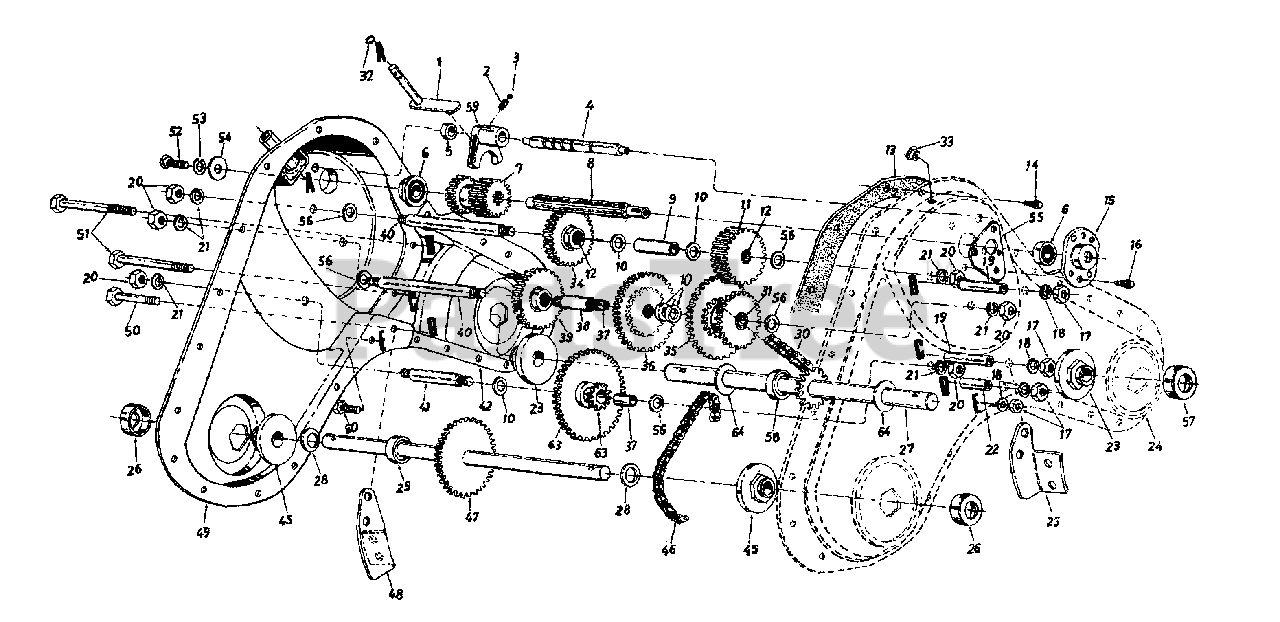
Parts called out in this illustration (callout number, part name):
1	Shifting Bracket Ass'y.
2	Compression Spring .50" Lg.
3	Ball Detent .250" Dia.
4	Detent Shaft 1/2" Dia.
5	Spacer .505" I.D. x .88" O.D.
6	Ball Brg. .62" I.D. x 1.38"
7	Spur Gear 16T (Input)
8	Input Spline Shaft 7/8"
9	Spacer .657" I.D. x 2.85" Lg.
10	Fl-Wash. .640" I.D. x 1.24"
11	Spur Gear 30T 7/8" I.D.
12	Needle Bearing 5/8" I.D.
13	Gasket--Trans. Hsg.
14	Hex S-Tap Scr. 1/4-20 x .5"
15	1-3/8" Dia. Bearing Housing
16	Hex TT-Tap Scr. 1/4-20 x .75"
17	Hex Nut 5/16-18 Thd.
18	L-Wash. 5/16" I.D.
19	Spacer 1.56" Lg.
20	Hex Nut 7/16-20 Thd.
21	Bell-Wash. .45" I.D. x 1.0"
22	Spacer 1.015" Lg.
23	Tine Shaft Brg. 1.002 x 2.50
27	Tine Shaft Ass'y. 1" O.D.
28	Fl-Wash. .76" I.D. x 1.5" O.D.
29	Spacer .75" I.D. x .50" Lg.
30	Chain #50 5/8 Pitch x 52 Links-Endless
31	Needle Bearing 5/8" I.D.
32	Snap Ring
33	Taper Cap Plug
34	Spur Gear 30T 12/16" I.D.
35	30/44T Gear Ass'y. Comp.
36	Spur Gear 44T/11T
37	Sleeve Bearing
38	Gear Hub 3/4" I.D. x 3" Lg.
39	Spur Gear 30T 1.0" I.D. x 1/2" W
40	Jack Shaft 5/8" Dia. x 5"
41	Jack Shaft 5/8" Dia. x 2.38"
45	Wheel Brg..752" x 2.5"
46	#420 Chain 1/2 Pitch x 50 Links-Endless
47	Wheel Shaft Ass'y. 15.6"
51	Hex Bolt 5/16-18 x 2.5"
52	Hex Bolt 1/4-20 x .62" Lg.
53	L-Wash. 3/8" I.D.
54	Fl-Wash. 1/4" I.D. x .93" O.D.
55	Gear Positioner Bracket
56	Fl-Wash. 7/16" I.D. x 1-3/8"
57	Seal 1" Shaft
58	Spacer 1" I.D. x 2" O.D.
59	Shifting Fork
60	Hex Bolt 5/16-18 x 1" Lg.
63	10T Sprocket Ass'y.
64	Thrust Wash. 1.03" I.D. x 1.62" O.D.
